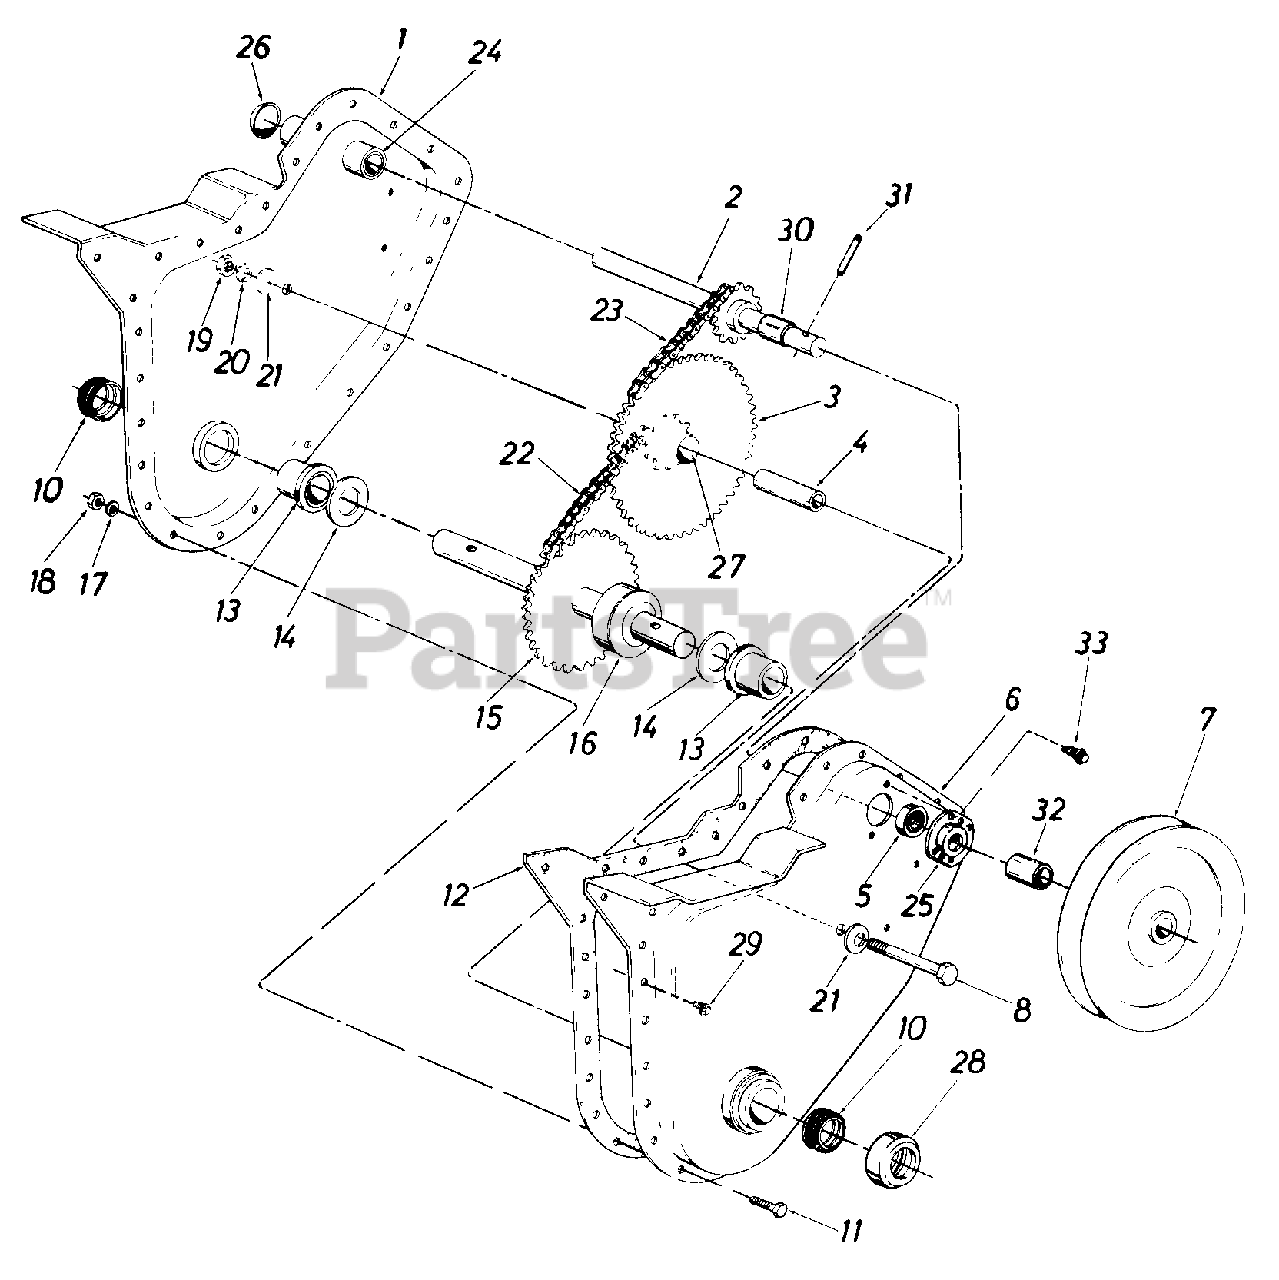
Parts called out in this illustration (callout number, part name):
1	Chain Case Ass'y.-R.H.
2	Input Shaft Ass'y.
3	Hub and Sprocket Ass'y.
4	Bearing Inner Race
5	Ball Bearing
6	Chain Case Ass'y.-L.H.
7	Pulley-Chain Case 5-1/2 x 1/2
8	Hex Bolt 3/8-24 x 2.50" Lg.
11	Hex Bolt 1/4-28 x .625" Lg.
12	Gasket
13	Flange Brg. .879 I.D.
14	Fl-Wash. .88 I.D. x 1.50 O.D. x .030
15	Tine Shaft Ass'y.
16	Spacer 7/8" I.D. x .68" Lg.
17	L-Wash. 1/4" I.D.
18	Hex Nut 1/4-28 Thd.
19	Hex Ins. L-Nut 3/8-24 Thd.
20	L-Wash. 3/8" I.D.
21	Bell-Wash. .406 I.D. x 1.130 O.D.
22	Chain #420-.50" Pitch x 38 Links
23	Chain #35-.375" Pitch x 50 Links
24	Bearing .62" I.D. x .813 O.D. x 1.31
25	Bearing Housing
26	Expansion Plug 13/16" Dia.
29	Hex Wash. Hd. Self-Tap Scr. 1/4-20 x .50" Lg.
30	Spacer .630" I.D. x .77" O.D. x.38" Lg.
31	Spring Pin Spiral 1/4" Dia. x 1-1/2 " Lg.
32	Spacer .647 x 1.25
33	Hex Wash. Hd. Self-Tap Scr. 1/4-20 x .38" Lg.
